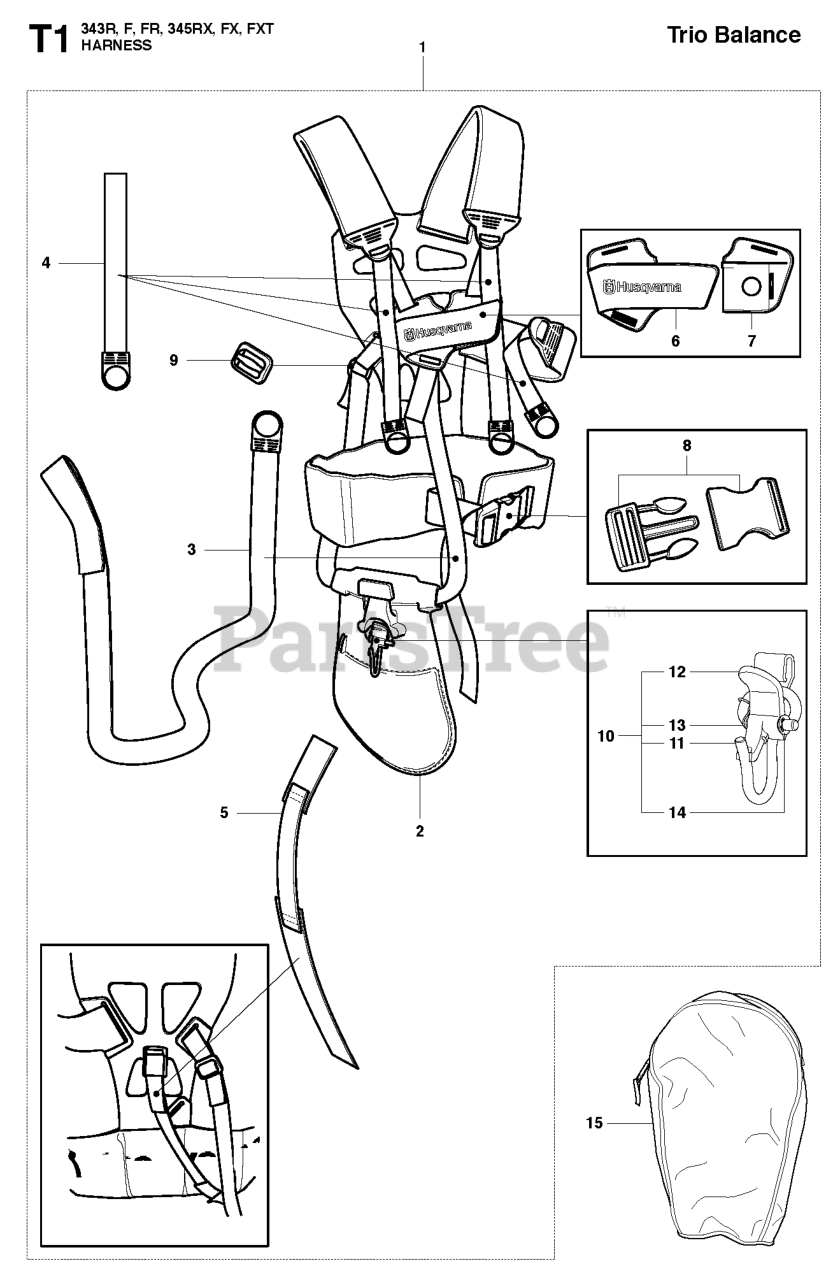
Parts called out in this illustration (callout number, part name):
1	RP HARNESS TRIO BALANCE
1	HUS BALANCE X TRIO HARNESS
6	FRONT PIECE
7	FRONT PIECE
9	RP CLIP
11	HOOK
12	CATCH *
13	SPRING
15	TOOL BAG
